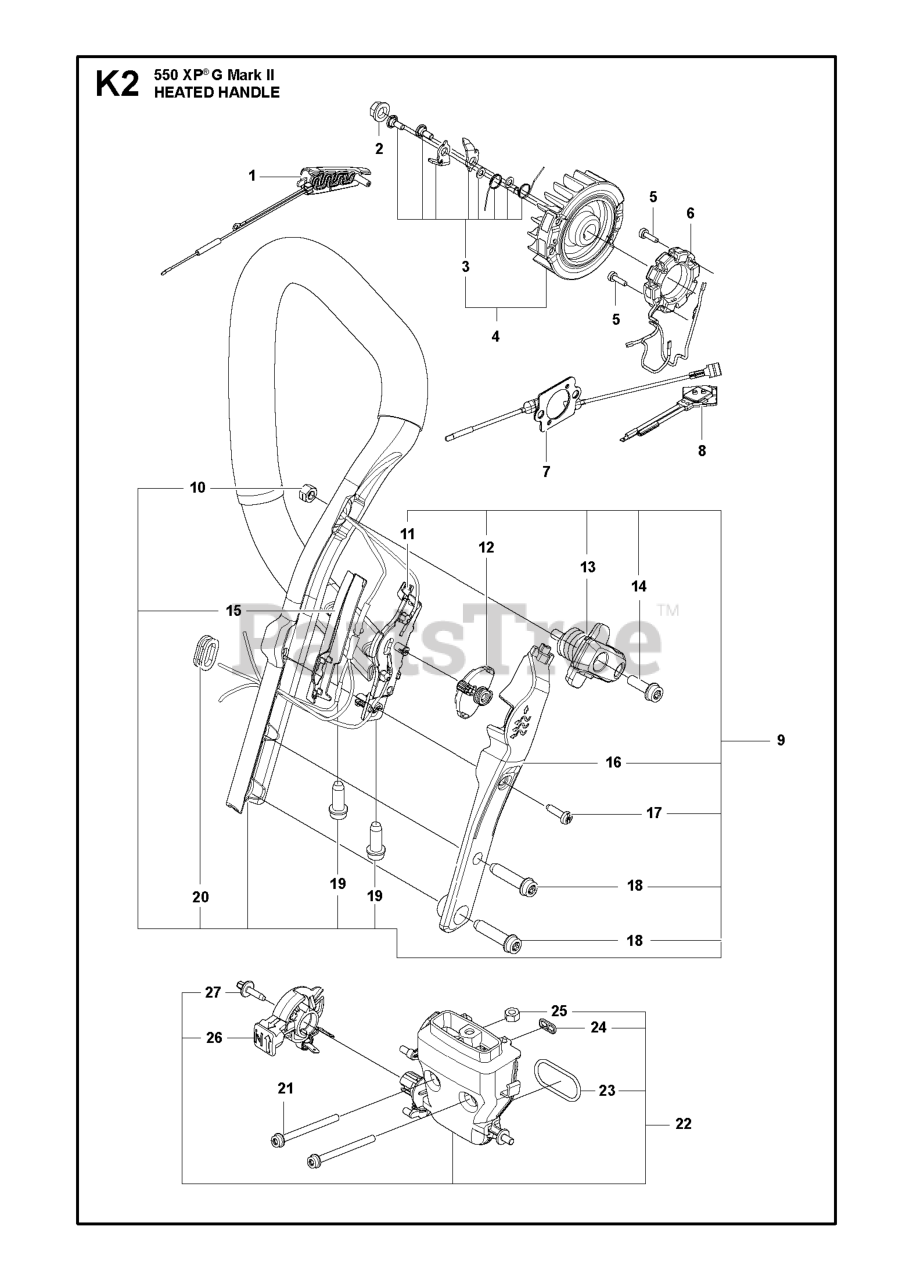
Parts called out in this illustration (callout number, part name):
1	HANDLE INSERT GEN 2 50CC
2	NUT W/ WASHER
3	SCREW KIT PAWL H550/545 MARK I
4	FLYWHEEL ASSY
5	SCREW ITXSCM M4X15 T27 12.9 T
6	STATOR ASSY GEN 2 50 CC
7	FOIL ELEMENT ASSY 50 CC GEN II
8	THERMOSTAT ASSY
9	HANDLE SYSTEM 50CC GEN 2 HEAT
11	CONTACT PLATE FRONT HANDLE HEA
13	ANTIVIBRATION ELEMENT ASSY ALU
15	PROTECTION FRONT HANDLE HEAT
16	CYLINDER COVER XP
19	SCREW ITXSCFT PL6X16 T27 10.9
21	SCREW ITXSCFM M4X50 T20 12.9
22	FILTER HOLDER ASSY HEAT HEAT
26	CHOKE CONTROL ASSY CHOKE/STOP
